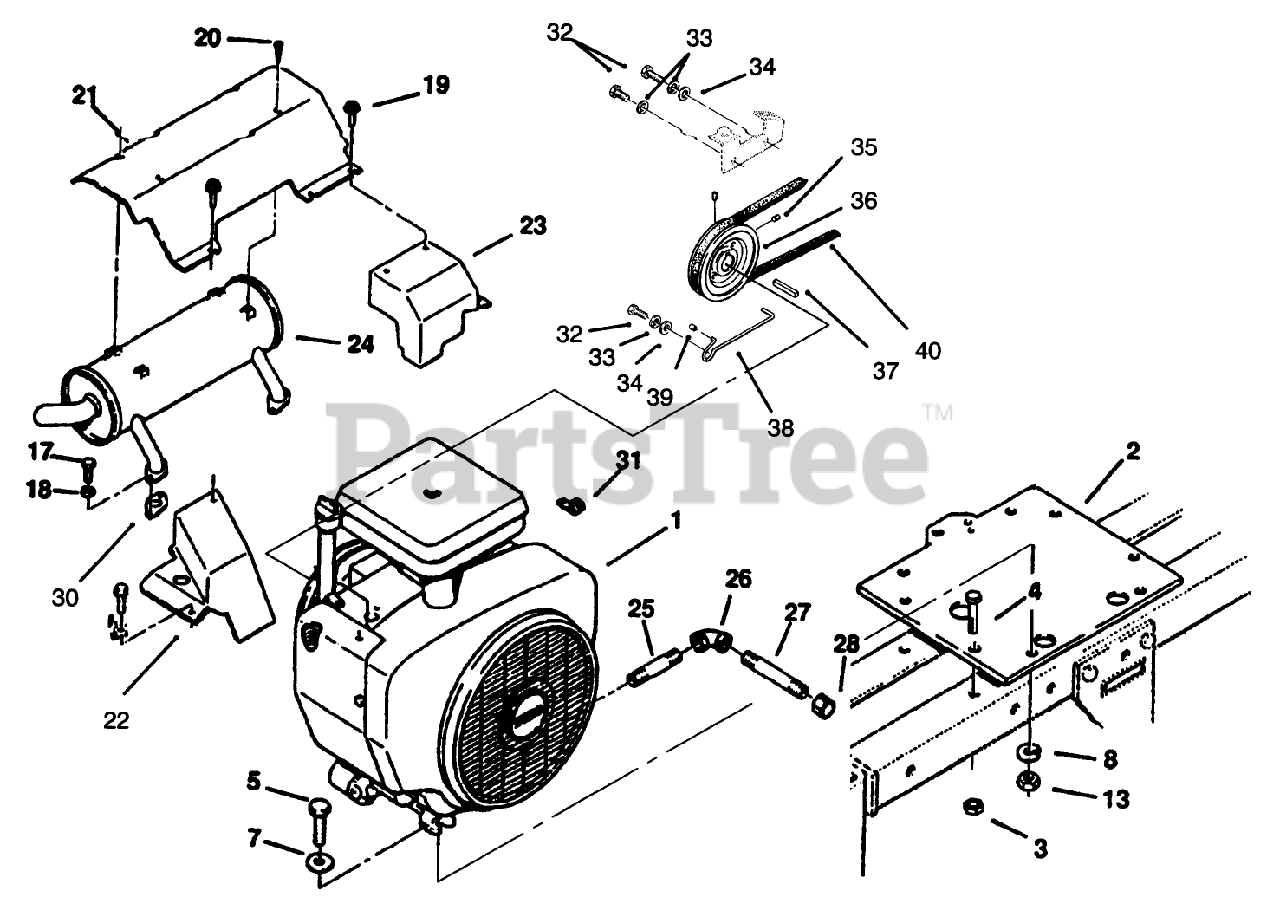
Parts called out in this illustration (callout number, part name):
2	PLATE-ENGINE *B
4	SCREW-HH
5	SCREW-HH
7	WASHER-FLAT
8	WASHER-LOCK
13	NUT-HEX
17	SCREW-HH
18	WASHER-LOCK
19	SCREW
20	SCREW
26	ELBOW 3/8 90 DEG
27	PIPE-NIPPLE 3/8 X 4"
28	CAP-PIPE
30	GASKET
31	J-CLIP
32	SCREW-HH
33	WASHER-LOCK
34	WASHER-FLAT
35	SCREW-SET, HSH
38	GUIDE BELT
40	BELT-V
